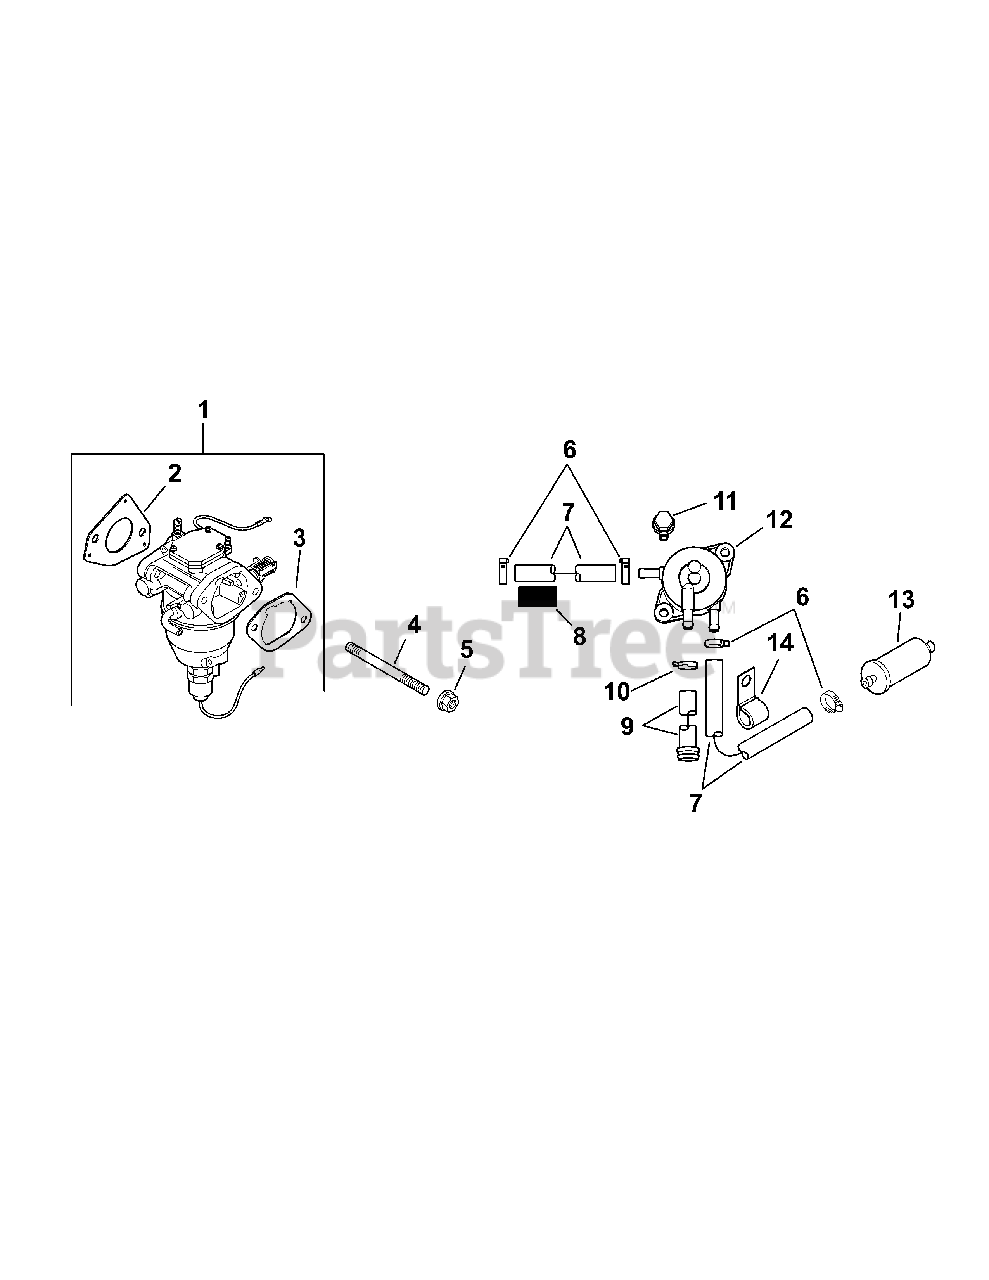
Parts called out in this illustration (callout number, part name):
1	KIT, CARBURETOR W/GASKETS
2	GASKET, CARBURETOR
3	GASKET, AIR CLEANER BASE
4	STUD, M6X1.0X106
5	NUT, FLG M6X1.0
6	CLAMP, SPRING HOSE 1/2"
7	LINE, FUEL
8	SLEEVE, ANTI ABRASION
9	KIT, FUEL PUMP HOSE W/CLAMP
11	SCREW, TAP M6X1.7X18
13	FILTER, FUEL
